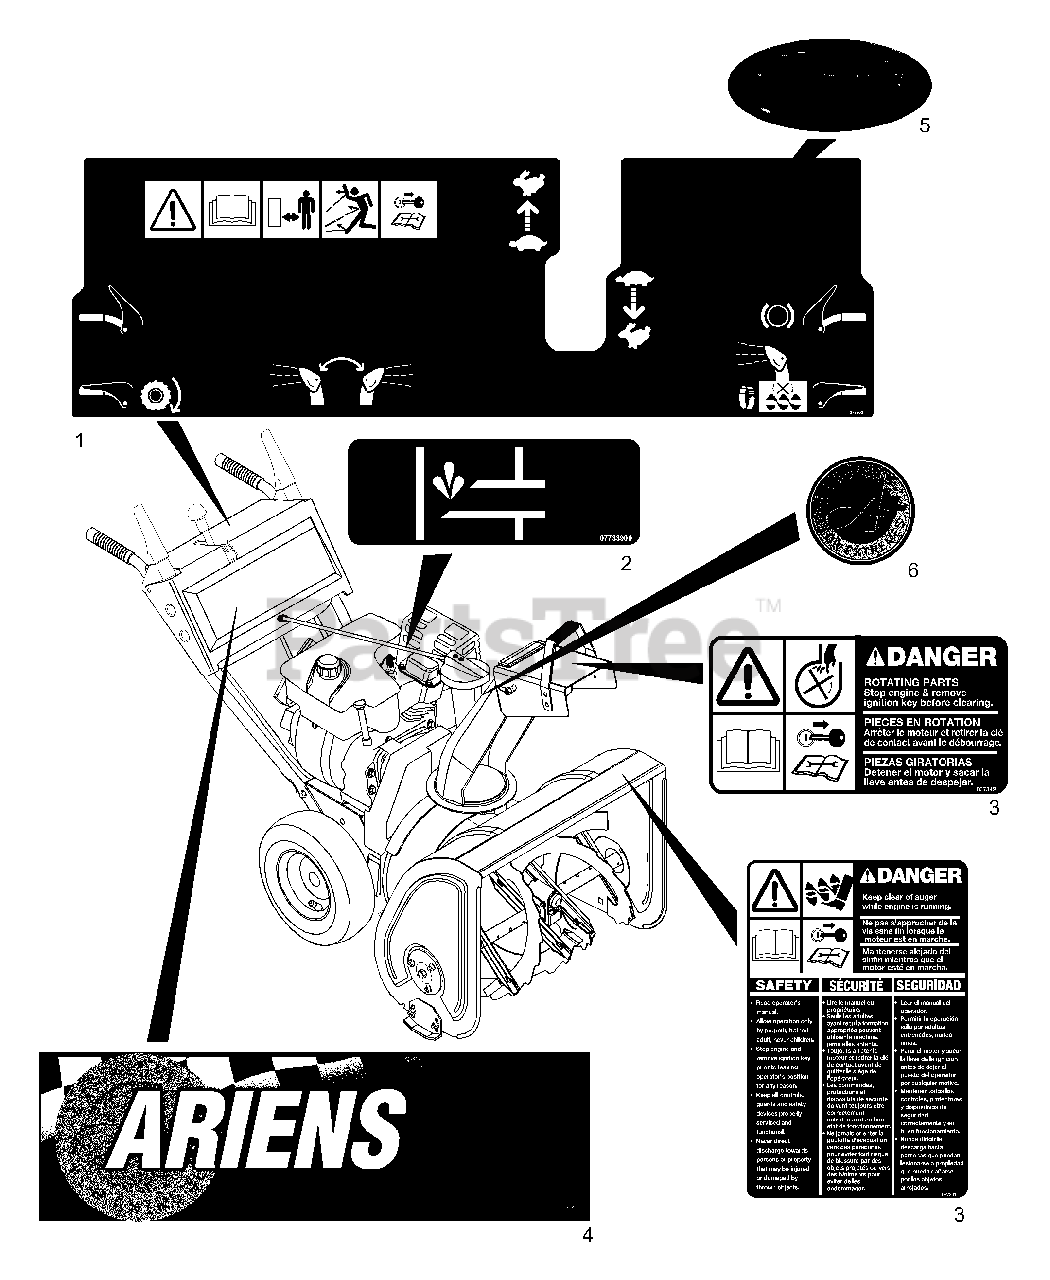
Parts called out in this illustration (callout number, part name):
1	DECAL, DASH
2	DECAL, PRIMER "TECUMSEH'S"
3	DECAL SET - DANGER
4	DECAL - ST724
5	DECAL, "ARIENS" JEWEL
6	DECAL, A+
